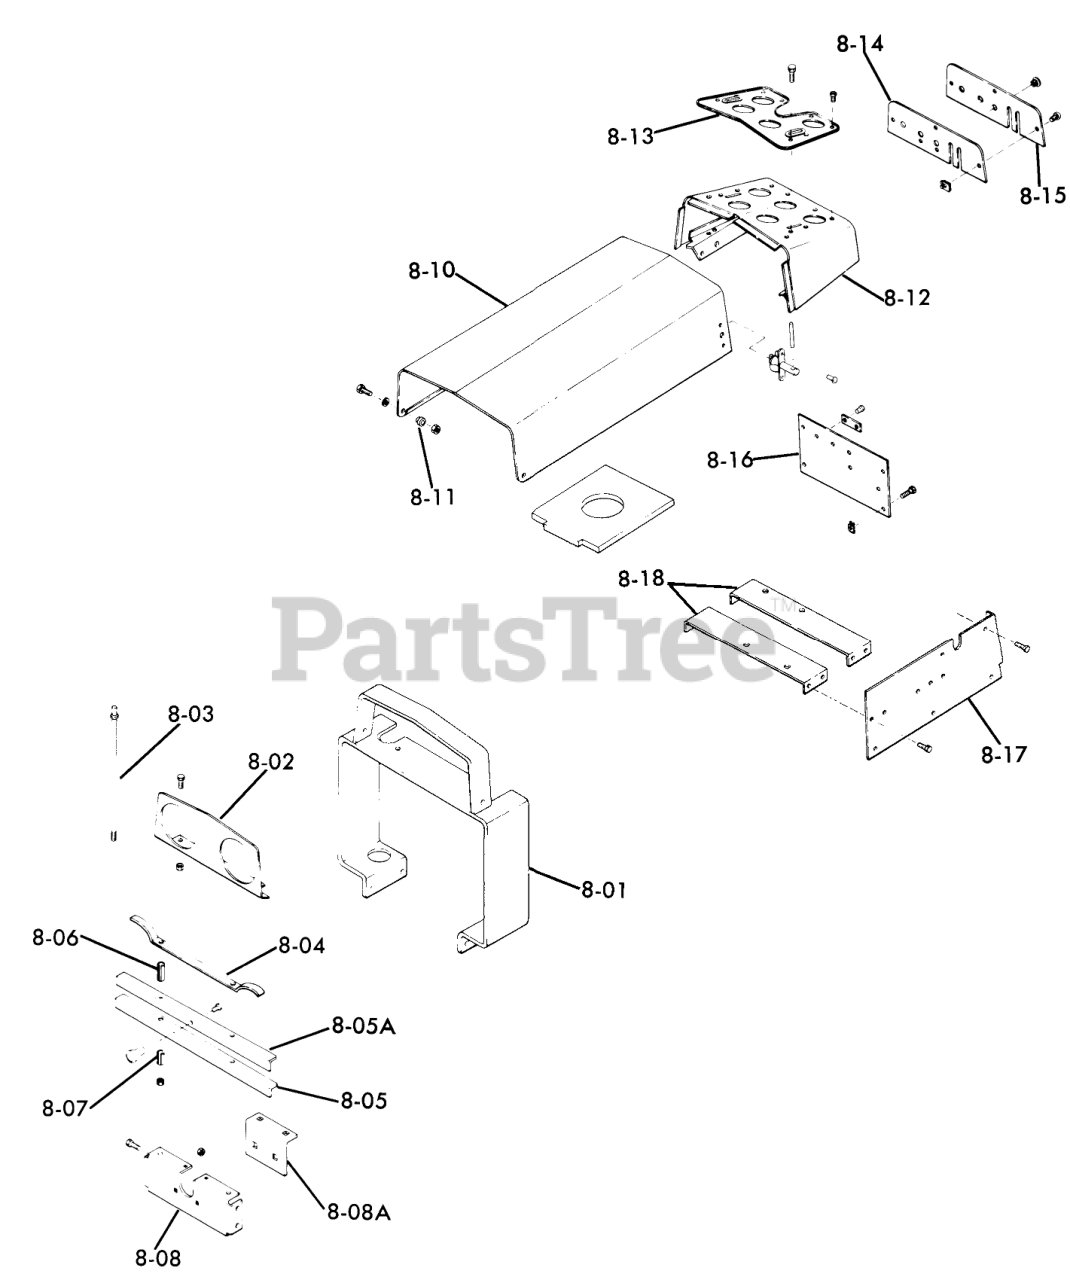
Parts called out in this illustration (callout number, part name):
8-01	Asy-Grille Shroud
8-02	Light Bracket
8-03	ROD-GRILLE
8-04	SPRING GRILLE
8-05	ANGLE-GRILLE
8-05A	ANGLE-GRILLE
8-06	Spacer
8-07	Spacer
8-08	Cover-Front
8-08A	Cover
8-10	Assy-Hood
8-11	Bushing
8-12	Control Housing
8-13	Plate Screws
8-13	Right Differential Gear
8-14	Plate
8-15	Plate-Rear Instrument
8-16	Panel
8-17	Panel-Console RH
8-18	Battery Support
8-19	Access Cover Plate
8-20	Plate-Fender RH
8-21	Fender
8-22	Channel
8-23	Footrest RH
8-24	Footrest Mat RH
8-25	Filler Plate
8-26	Bracket
